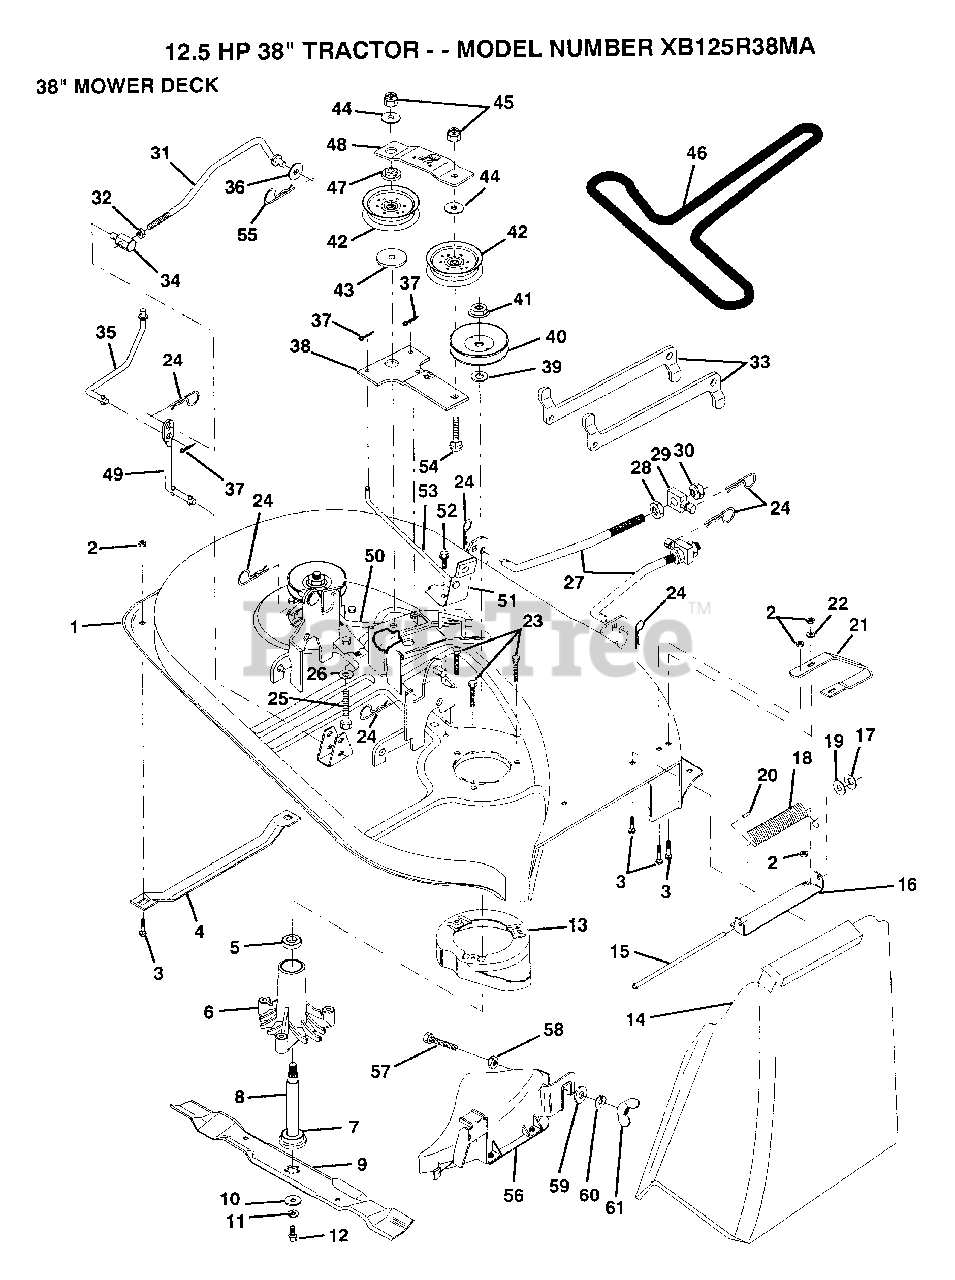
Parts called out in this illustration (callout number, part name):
1	MOWER DECK ASSY
3	BOLT
4	RUNNER-LH M
5	BEARING
6	HSG ASM MANDREL
7	BEARING.BALL
9	"BLADE.38""V.MULCH"
10	WASHER BLADE
12	BLADE BOLT
14	DEFLECTOR-SHLD T
15	ROD-HINGE T
17	NUT PUSH M
19	WASHER
20	CAP-SLEEVE LT
21	RUNNER RH
22	WASHER M
25	BOLT
26	WASHER GT
27	SEAL.COVER.BAGGER
28	NUT
29	TRUNION
30	NUT.LK.W/WSH.1/2.
31	CLUTCH ROD PRI
32	NUT
33	SUSP ARM REAR
34	TRUNNION
35	CLUTCH ROD SEC
36	WASHER HYT
38	IDLER ARM ASSY
39	WASHER
42	FLAT IDLER PULLEY
43	SPACER RETAINER
44	WASHER GT
46	BELT-V.88.12.MW
47	RETAINER SPACER
48	IDLER ARM STIFF
49	PIVOT ROD
50	BRAKE ROD LH
51	BRAKE ASM
52	SCREW
53	BRAKE ROD RH
54	BOLT
55	RETAINER M
56	COVER.MULCHER
57	HEX BOLT
60	LOCKWASHER
61	WINGNUT
